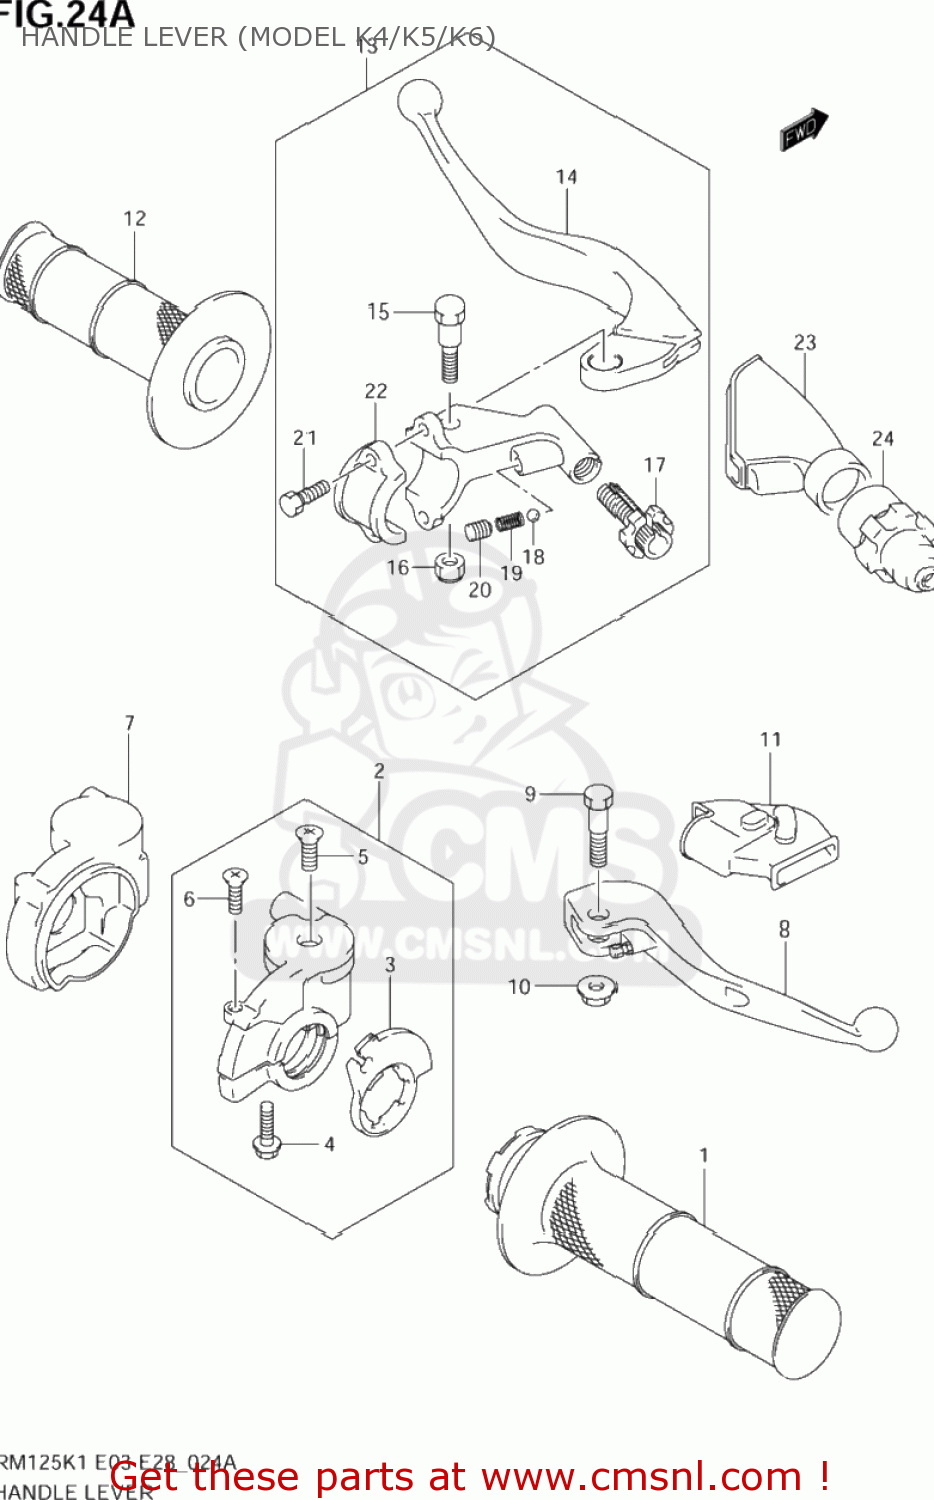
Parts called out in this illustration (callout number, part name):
1	GRIP,THROTTLE
2	CASE ASSY,THROTTLE
3	ROTOR,THROTTLE
4	SCREW
5	SCREW,UPPER
6	SCREW
7	COVER,THROTTLE CASE
8	LEVER ASSY,BRAKE
9	BOLT,BRAKE LEVER
10	NUT
11	COVER,BRAKE LEVER
12	GRIP,L
13	LEVER ASSY,CLU
14	LEVER,CLUTCH
15	BOLT,LEVER PIVOT
16	NUT 6MM
17	ADJUSTER,CLUTCH CABLE
18	BALL
19	SPRING
20	SCREW(6X8)
21	BOLT(6X16)
22	HOLDER
23	COVER,CLUTCH LEVER
24	COVER,CLUTCH ADJUSTER
